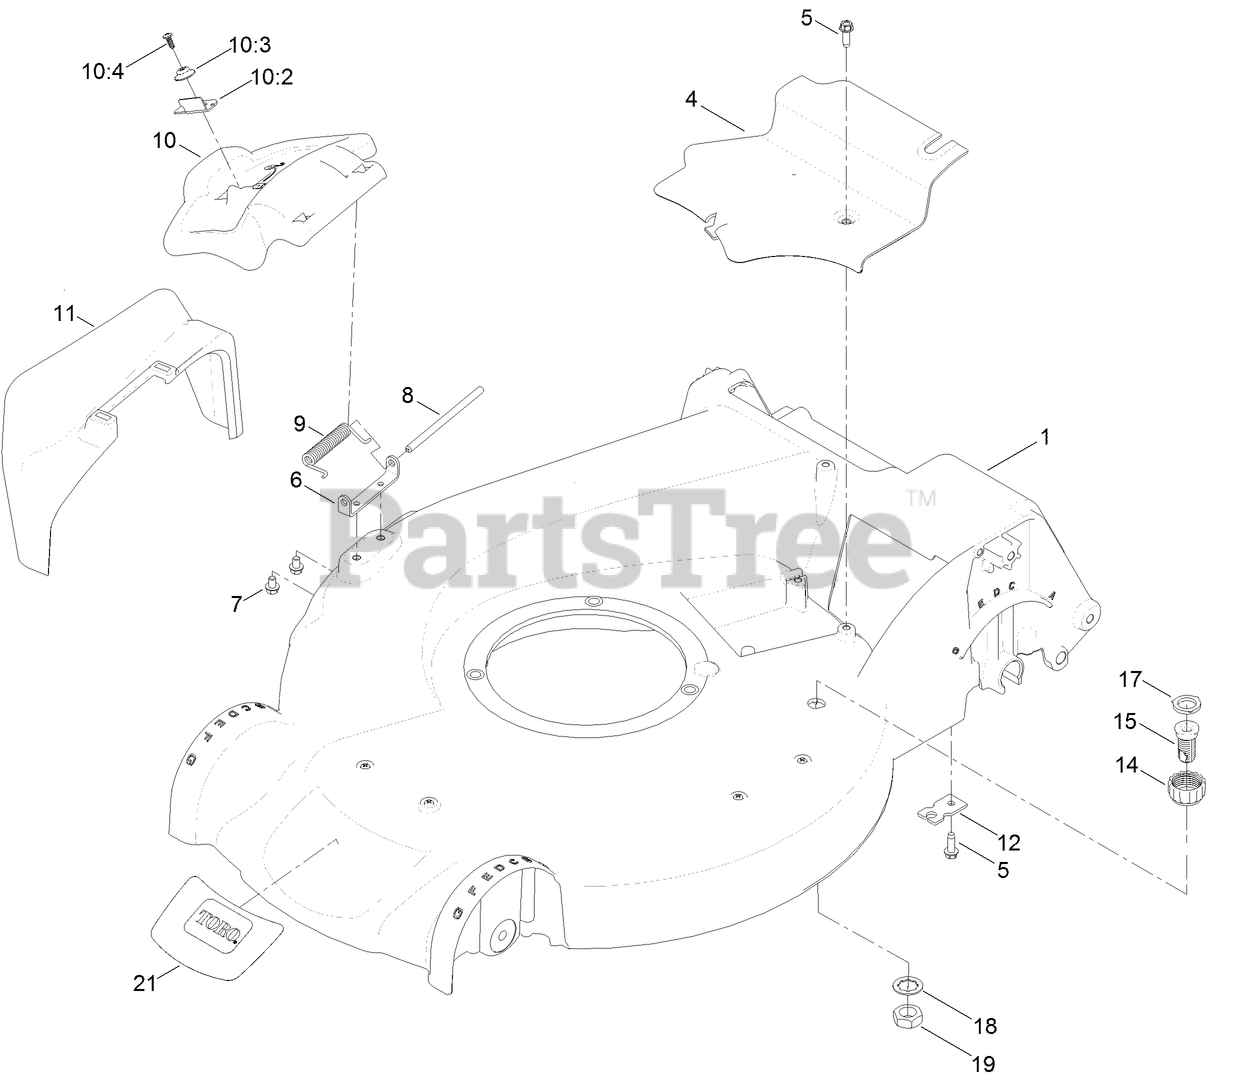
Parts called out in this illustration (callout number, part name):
1	HOUSING ASM
4	COVER-BELT
5	SCREW-HWHTF
6	BRACKET-COVER
7	SCREW-HWH
8	ROD-COVER
9	SPRING-TORSION
10	DISCHARGE DOOR ASM
10:2	LATCH-DOOR
10:3	CAP-DOOR
10:4	SCREW-PLASTITE
11	CHUTE-DISCHARGE, SIDE
12	BRACKET-CABLE, TRACTION
14	COUPLING-HOSE, WASHOUT PORT
15	PORT-WASHOUT
17	WASHER-SEAL, WASHOUT PORT
18	WASHER-TOOTH, INTERNAL
19	NUT-JAM
21	DECAL-DECK
